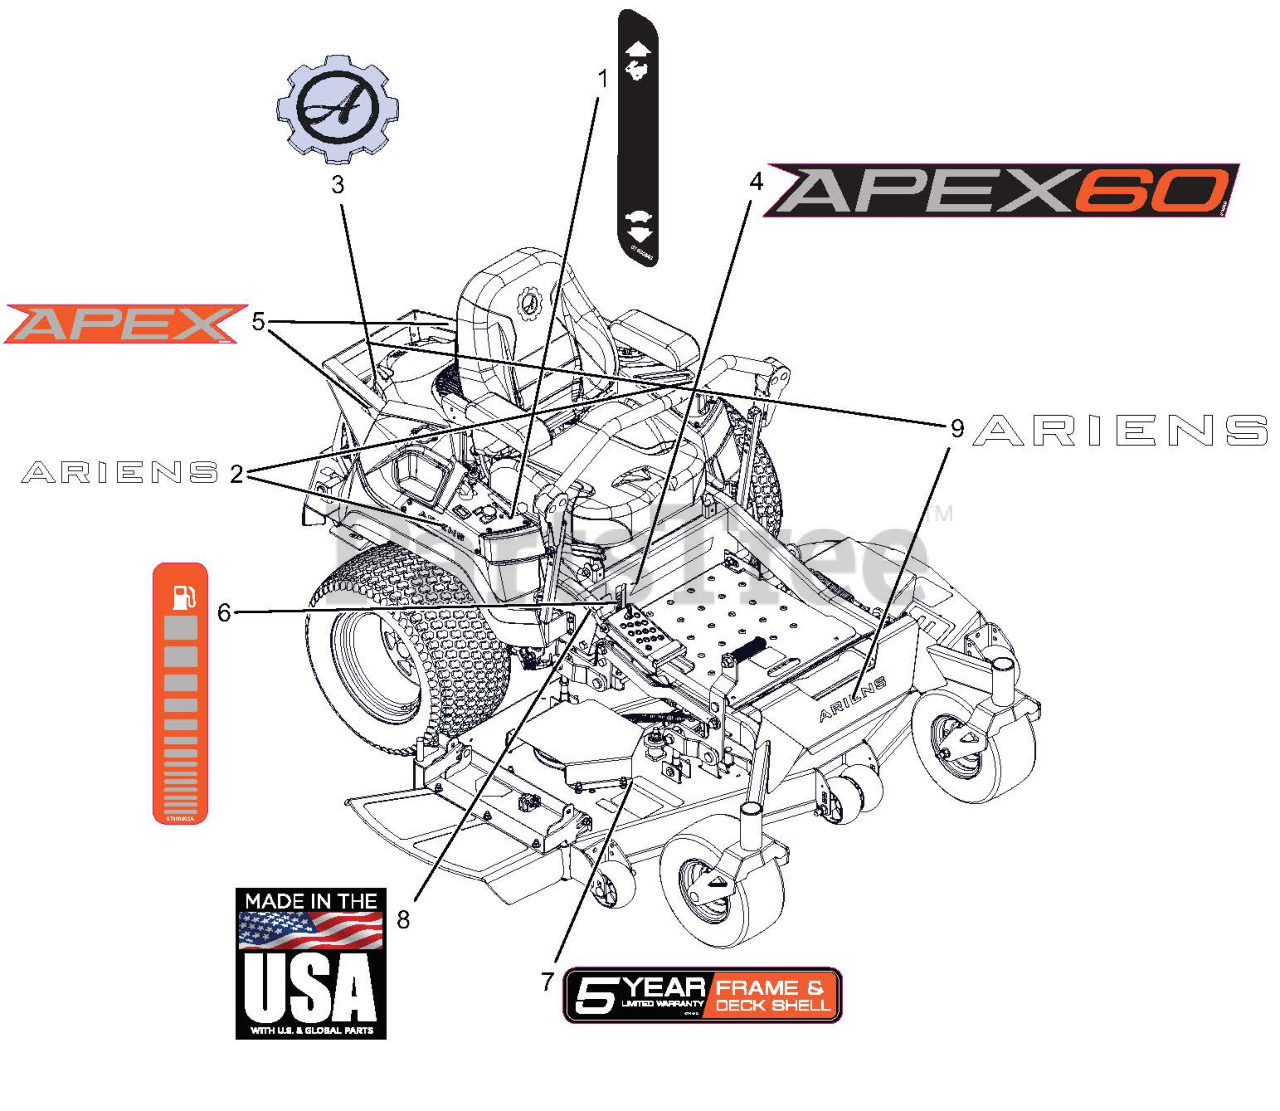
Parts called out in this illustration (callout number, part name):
1	DECAL, DASH DECAL
2	DECAL, ARIENS (6.50")
3	DECAL, ARIENS-GEAR BADGE -THK
4	DECAL, 60" APEX KICKPLATE
5	DECAL, APEX FENDER
6	DECAL, ARIENS FUEL LEVEL
7	DECAL, DECK 5 YEAR-ARIENS
8	DECAL, MADE IN USA
9	DECAL - ARIENS 9.625"
